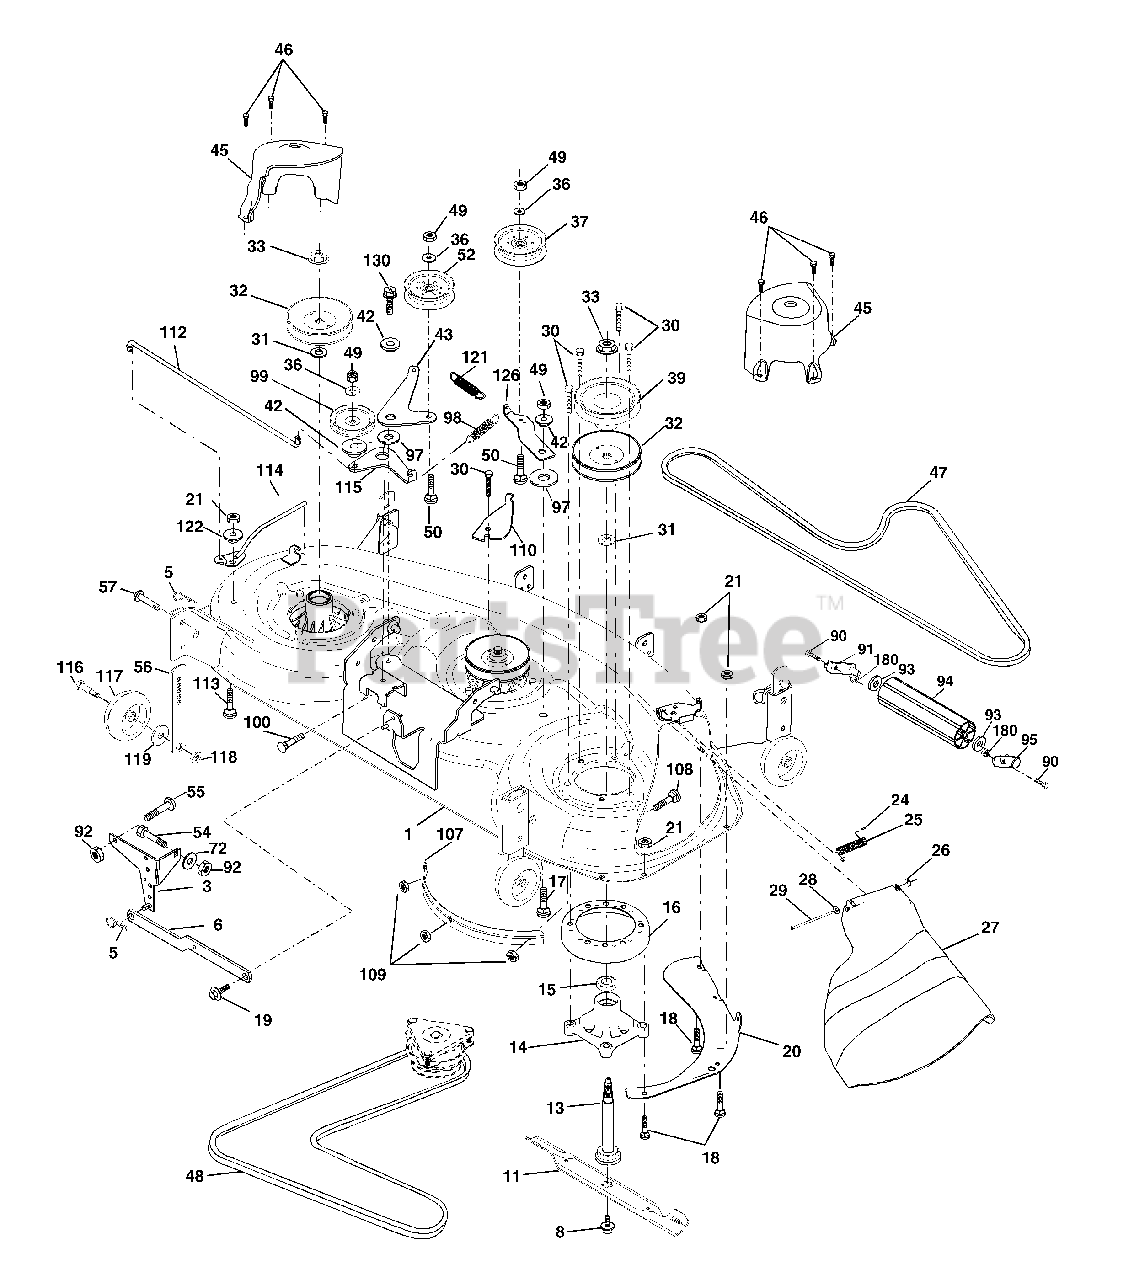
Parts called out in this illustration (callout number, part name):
1	Deck Weldment Mower 48
3	Bracket Asm., Sway Bar
5	Retainer Spring
6	Arm, Suspension, Rear (Sway Bar)
8	Bolt 7/16 Asm. Blade
11	Blade
13	Shaft Asm. w/Lower Bearing
14	Mandrel Asm.
15	Bearing, Ball, Mandrel
16	Stripper Mandrel Deck
17	Bolt RDHD Sq Neck 3/8-16 x 1.25
18	Bolt, Carriage 5/16-18 x 5/8
19	Bolt, Hex Hd, Shoulder 5/16-18
20	Baffle, Vortex Mower
21	Nut, Crownlock 5/16-18 UNC
24	Cap, Sleeve
25	Spring, Torsion
26	Nut, Push
27	Deflector Shield
28	Washer 11/32 x 5/8 x 16 Ga.
29	Rod, Hinge
30	Screw, Thdroll Washer Head
31	Washer, Spacer Mower Vented
32	Pulley, Mandrel
33	Nut, Flg. Top Lock Cntr. 9/16
36	Washer 13/32 x 13/16 x 16 Ga.
37	Pulley, Idler, Flat
39	Pulley, Idler, Driven
42	Spacer, Retainer
43	Arm, Idler Secondary
45	Cover, Mandrel Deck
46	Screw, Thdroll. 1/4-20 x 5/8
47	V-Belt, Mower, Secondary
48	V-Belt, Mower, Primary
49	Nut, Crownlock 3/8-16 UNC
50	Bolt, Carr. 3/8-16 x 1-1/2 Gr. 5
52	Pulley Idler Flat
54	Bolt Fin Hex 3/8-16 x 1
55	Bolt Carriage Sqnk. 3/8-16 x 1
56	Bar Pnt Adj.
57	Pin Head Rivet
72	Washer 13/32 x 13/16 x 12 Ga.
90	Bolt, Hex Hd 5/16-18 x 1
91	Bracket, Asm Noseroller, LH
92	Nut Lock Hex 3/8-16
93	Washer 17/32 x 7/8 x 16
94	Noseroller
95	Bracket, Asm Noseroller RH
97	Washer Hardened
98	Spring Primary Drive
99	Pulley Idler "V"
100	Bolt RDHD Sqnk 3/8-16 UNC x 2
107	Baffle Vac Edge Mower
108	Bolt Carr.
109	Nut Crownlock 1/4-20
110	Arm Spring Secondary
112	Link Tension Relief Lever
113	Bolt Carr. 5/16-18 x 1
114	Tension Asm. Relief Lever
115	Arm Spring Tension Relief
116	Bolt, Shoulder
117	Gauge Wheel
118	Nut, Centerlock 3/8-16 UNC
119	Washer 3/8 x 7/8 x 14 Ga.
121	Spring Secondary Drive
122	Bushing Pivot Tension Relief
126	Arm, Idler, Primary Deck
130	Screw 3/8-16 x 1.0
180	Nut Lock 5/16-18
